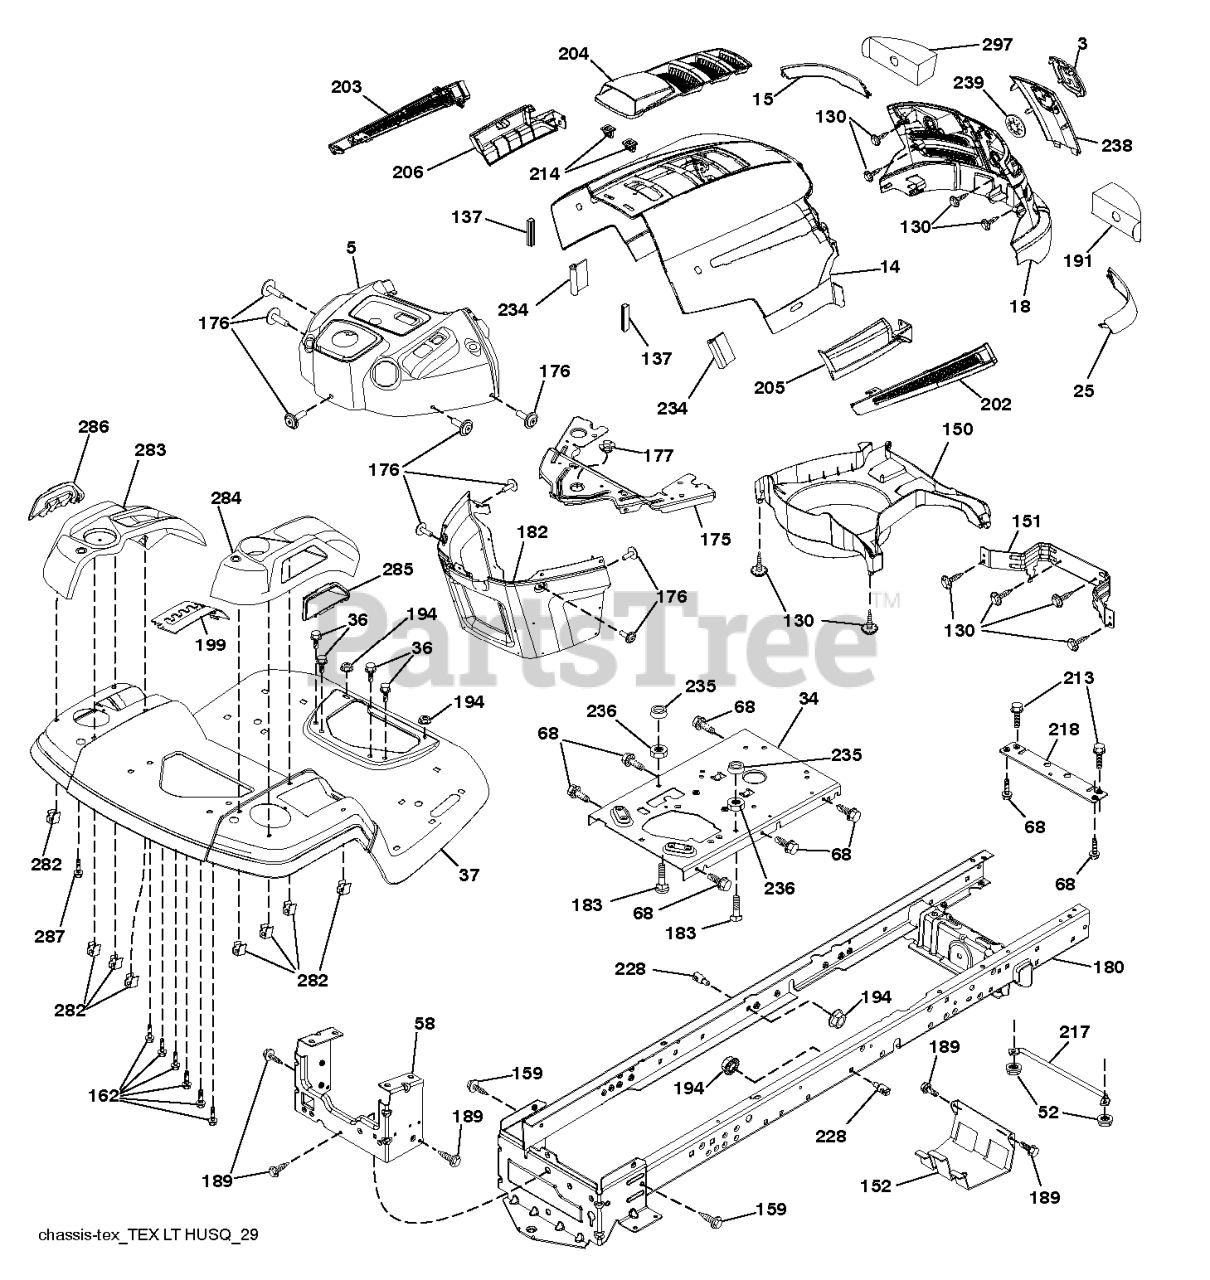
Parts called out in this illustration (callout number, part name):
3	RP LOGO
14	HOOD.HUSQVARNA.LT.ORANGE
15	LENS.HUSQVARNA LT.LH
18	GRILLE.SVC.HUSQVARNA.LT.GREY
25	LENS.HUSQVARNA LT.RH
34	PLATE.ENGINE.WELDED.CHASSIS
36	SCREW 5/16"
37	FENDER.TLT.FS.W/CUPHLD.ORANGE
52	LOCKNUT
58	DRAWBAR UPPER 2PC SMALL FENDER
68	Screw 5/16-18 x 1/2 Hex, Self Tapping 5/16-18 x 1/2
130	SCREW.#10 X 0.750.BOS
137	BUMPER DASH
151	BRACKET PIVOT
152	SHIELD.BROWNING.W/TEX
159	SCREW, 3/8-16X3/4
162	SCREW.HI-LO.CONSOLE
175	CROSSMEMBER
176	SCREW.#10-24X5/8.RN.QU
177	BUSHING STEERING
180	CHASSIS.WLDMNT.14GA.2PC.18".TI
182	DASH.LOWER.PREDATOR LT
183	BOLT.5/16-18X1-1/4 FULL THD
189	SCREW
191	INSERT.REFLECTIVE.RH.
194	NUT LOCK HEX FLANGE 5/16-18
199	PLATE.DECK.LIFT.HUSQ.LT
202	VENT.SIDE.HUSQVARNA.LT.RT
203	VENT SIDE HOOD RH
204	VENT TOP HOOD
205	SKIRT SIDE RH
206	SKIRT SIDE LH
213	BOLT
214	CLIP.RETAINER.TINNER.
217	ROD.PIVOT.HOOD
218	X-PIECE.HOOD.STOP.NON/
228	STUD.FASTNER.W/ANTI-ROTATE
234	BUMPER.HOOD.TEX.HUSQVARNA
235	SPACER FENDER
236	NUT.CENTERLOCK.5/16-
238	TRIM
282	CLIP.RETAINER.CONSOLE.LT.HUSQ
283	CONSOLE.DECK.LIFT.HUSQ.N/FR.GR
284	CONSOLE.CNTRL.
285	CONSOLE INSERT RH
286	CONSOLE.INSRT.LH.HUSQ.LT.BLACK
287	SCREW 1/4X20
297	INSERT REFLECTIVE
